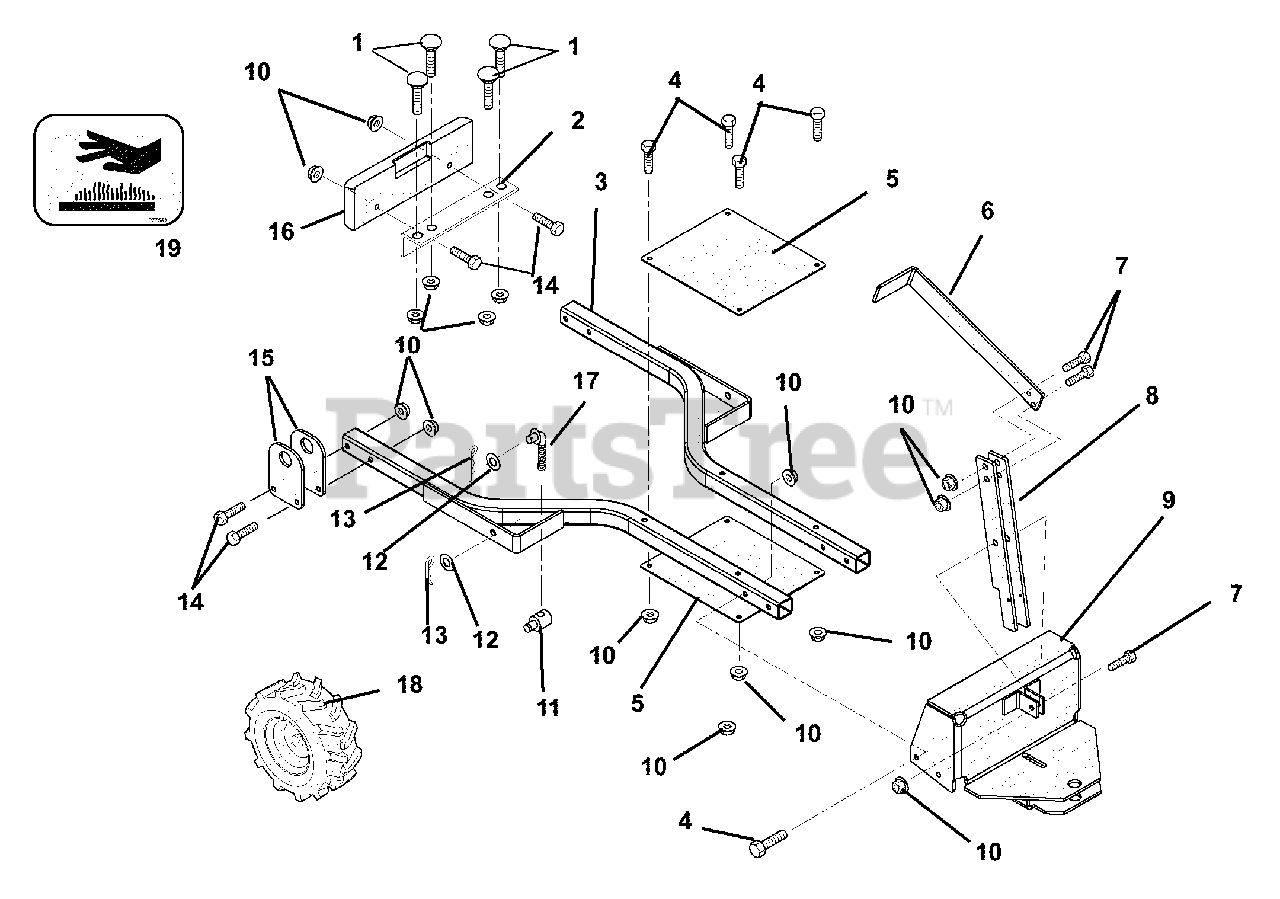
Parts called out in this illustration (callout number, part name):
1	@BLT-RDHDSQNK .38-16X2.50 G5YZ
2	BRKT,ANGLE
3	WMT,SUB-FRAME TUBE
4	@BLT-HEX .38-16X2.25 GR5 YWZC
5	PLATE,SUB-FRAME
7	@BLT-HEX .38-16X1.25 GR5 YWZC
9	YOKE,BLADE MOUNT
10	@NUT-LK-TOP-FLG .38-16 YWZC
11	TRUNNION-.50
12	WSHR-FL-STL .531X1.250X.10 YWZ
13	PIN, HAIR, EXT - #16 YWZC
14	@BLT-HEX .38-16X2.50 GR5 YWZC
15	BRKT,PIVOT
16	WEIGHT, CAST IRON
17	LINK, LIFT
18	ASSY,WHEEL & TIRE 18X6.5 S-HOG
19	DECAL, HOT SURFACE
